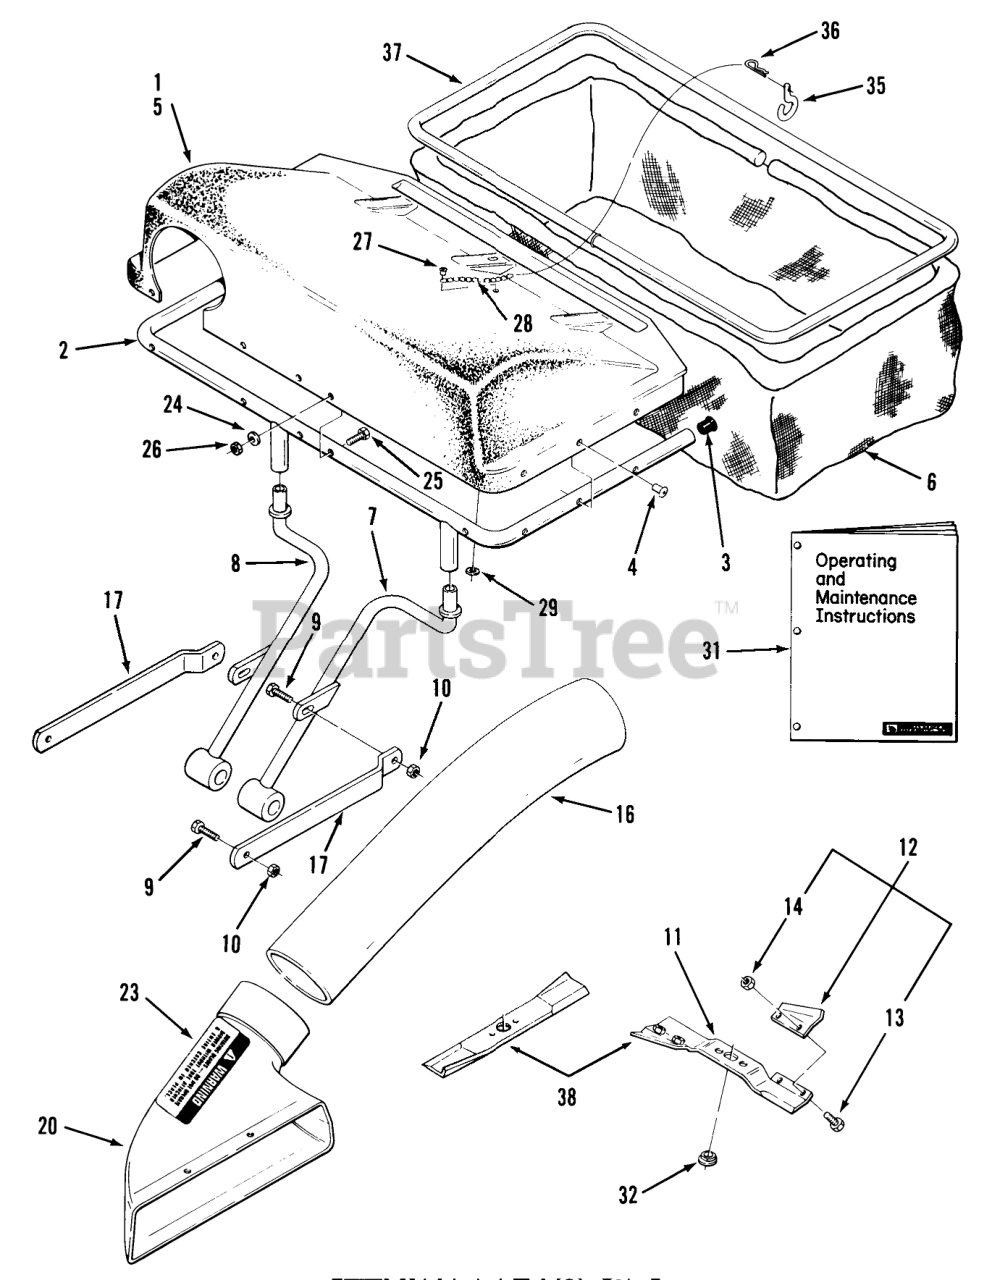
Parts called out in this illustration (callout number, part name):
4	Poprivet 3/16 dia. x .575
7	ASSY QUICK ATTACH *B
11	ASSY-HI LIFT BLADE
12	S/A 37 LIFT TAB KIT
13	BOLT 5/16-18X5/8
14	NUT-HEX
16	CHUTE 37" BAGGER
27	RIVET
31	Operating and Maintenance Instructions
32	SPACER BLADE
36	Hairpin Cotter
37	FRAME-BAG *B
38	KIT-BLADE (SERVICE)
